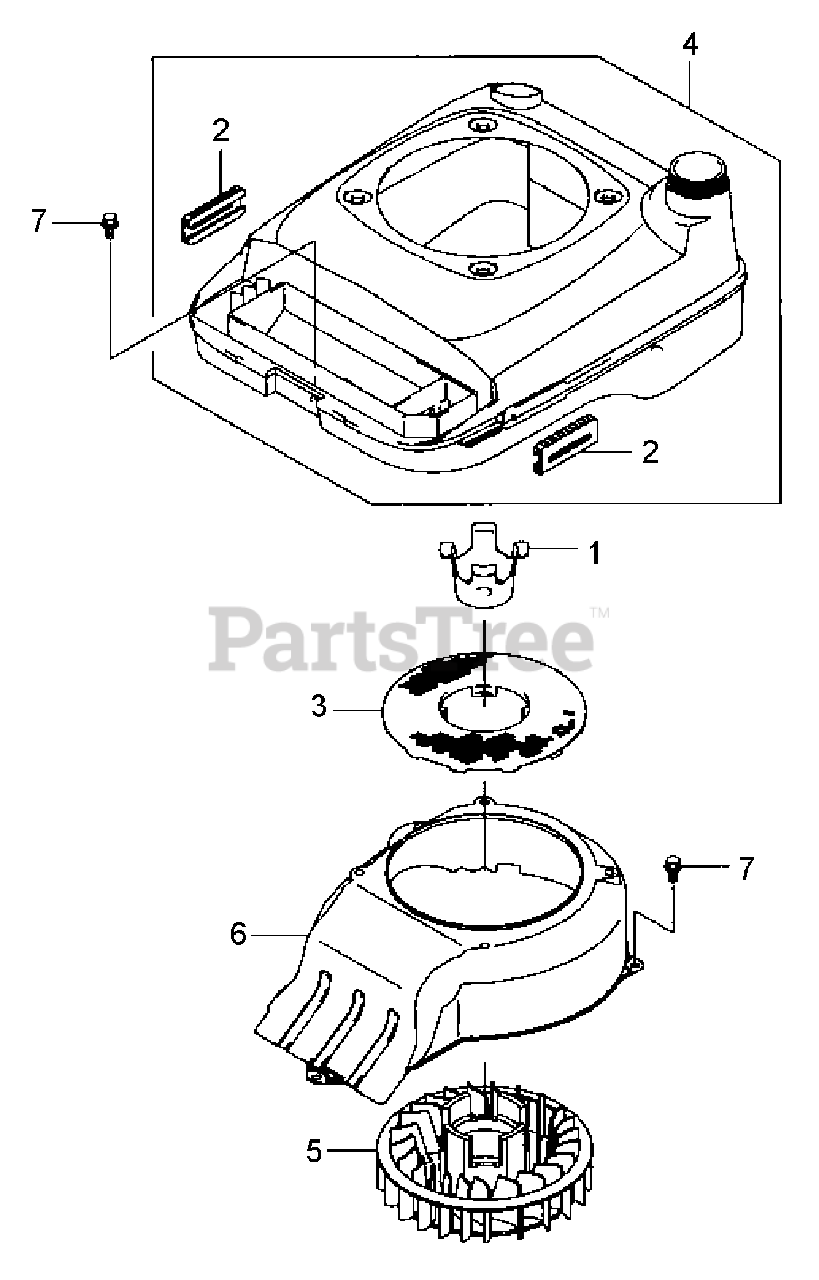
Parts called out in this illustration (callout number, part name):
3	Screen
4	Cover
5	Fan
6	Fan Housing
7	Flanged Bolt
